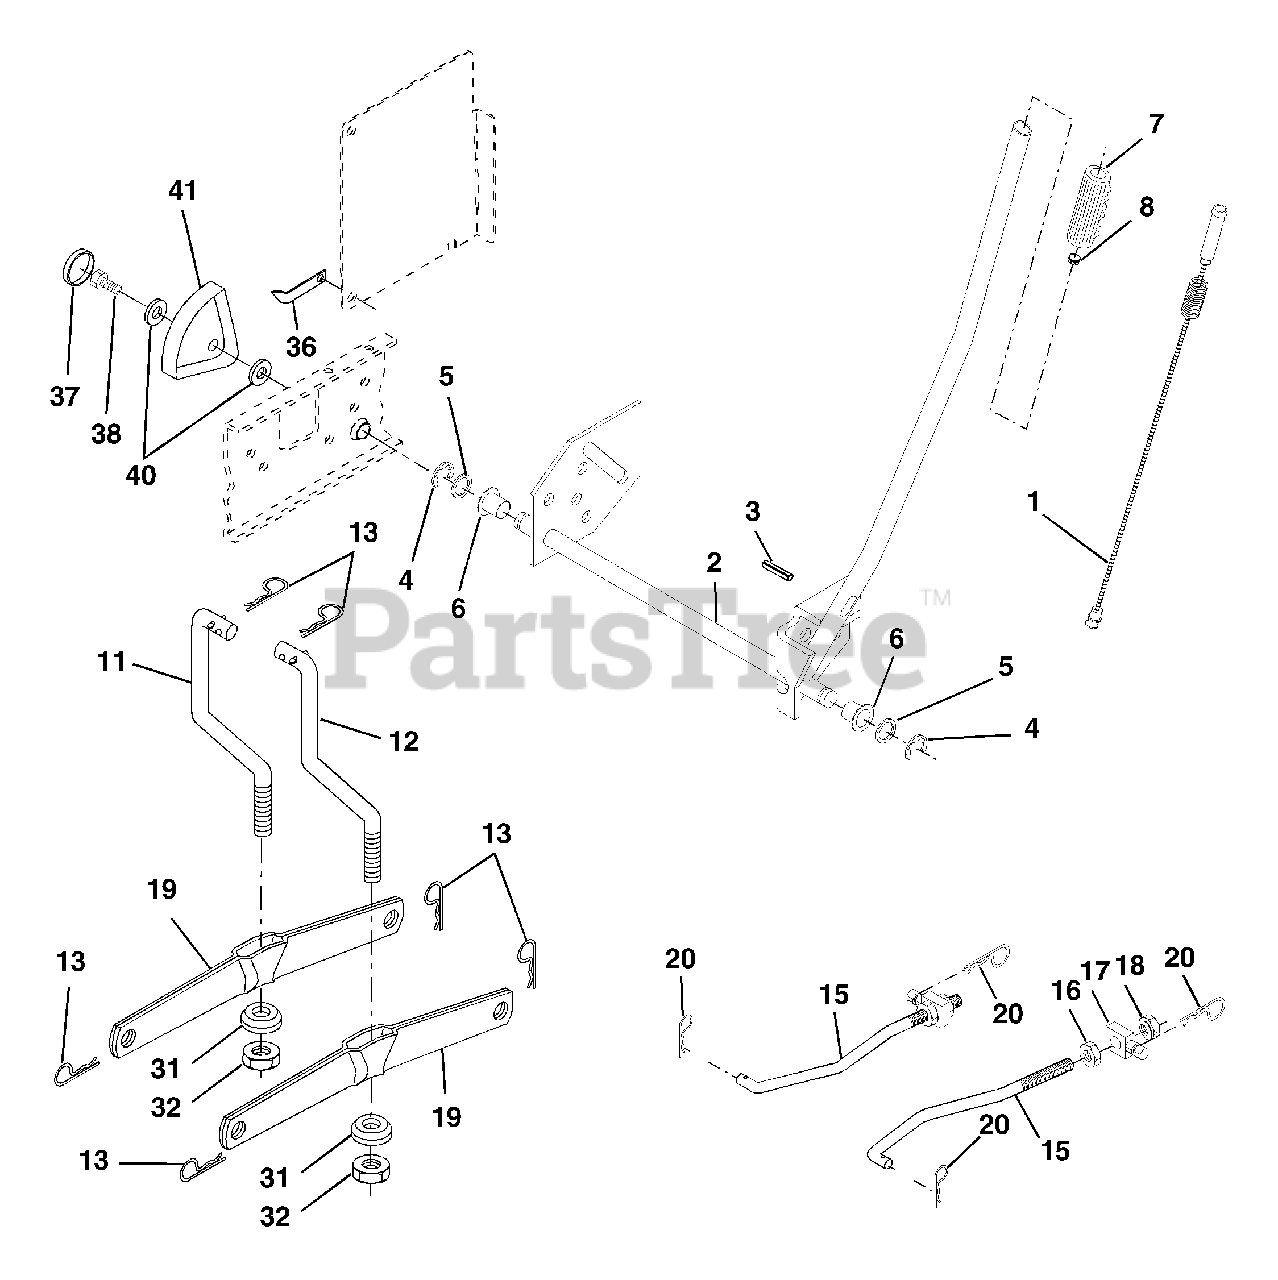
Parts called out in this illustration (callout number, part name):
1	Wire Asm Inner/Sprg W/plunger LT
2	Shaft Asm Lift RH w/Inf
3	Pin Groove 1 500 Zinc
4	E Ring #5133-62
5	Washer 21/32 X 1 X 21 Ga
6	Bearing Nylon Blk 629 Id
7	Grip Handle
8	Button Plunger
11	Link Lift LH Fixed Length
12	Link Lift RH Fixed Length
13	Retainer Spring
15	Link Front
16	Nut Jam Hex 1/2-13 Unc
17	Trunnion Blk Zinc
18	Nut Lock W/Wsh 1/2-13 Unc
19	Arm Suspension Rear
20	Retainer Spring
31	Bearing Pvt Lift
32	Nut Crownlock 3/8 - 24
36	Pointer Height Indicator
37	Plug Hole Blk. 1.485/1.515 Dia.
38	Screw 5/16-18 x 1
40	Washer 11/32 x 1-1/210 Ga.
41	Indicator Height STLT
